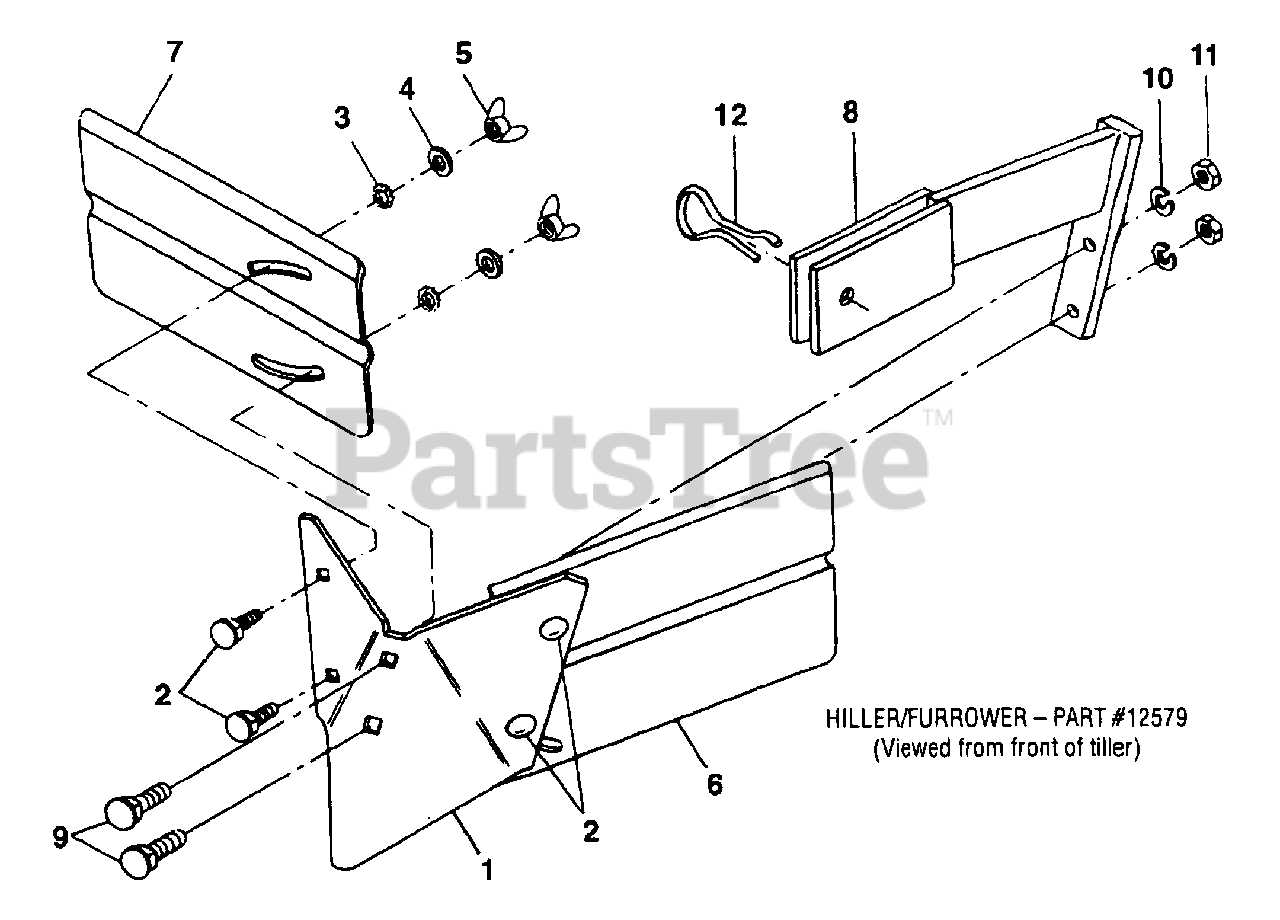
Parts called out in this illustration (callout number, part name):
1	Furrower-blade only
2	Carriage Bolt-5/16-18 x 3/4
3	Star Washer-external tooth, 5/16
4	Plain Washer-5/16 S.A.E.
5	Wing Nut-5/16-18
6	Hiller Wing - left
7	Hiller Wing - right
8	Bracket-blade mounting
9	Carriage Bolt-blade mounting, 3/8-16 x 1-1/2
10	Lockwasher-3/8, plated
11	Nut-hex, 3/8-16, plated
12	Pin-clinch
